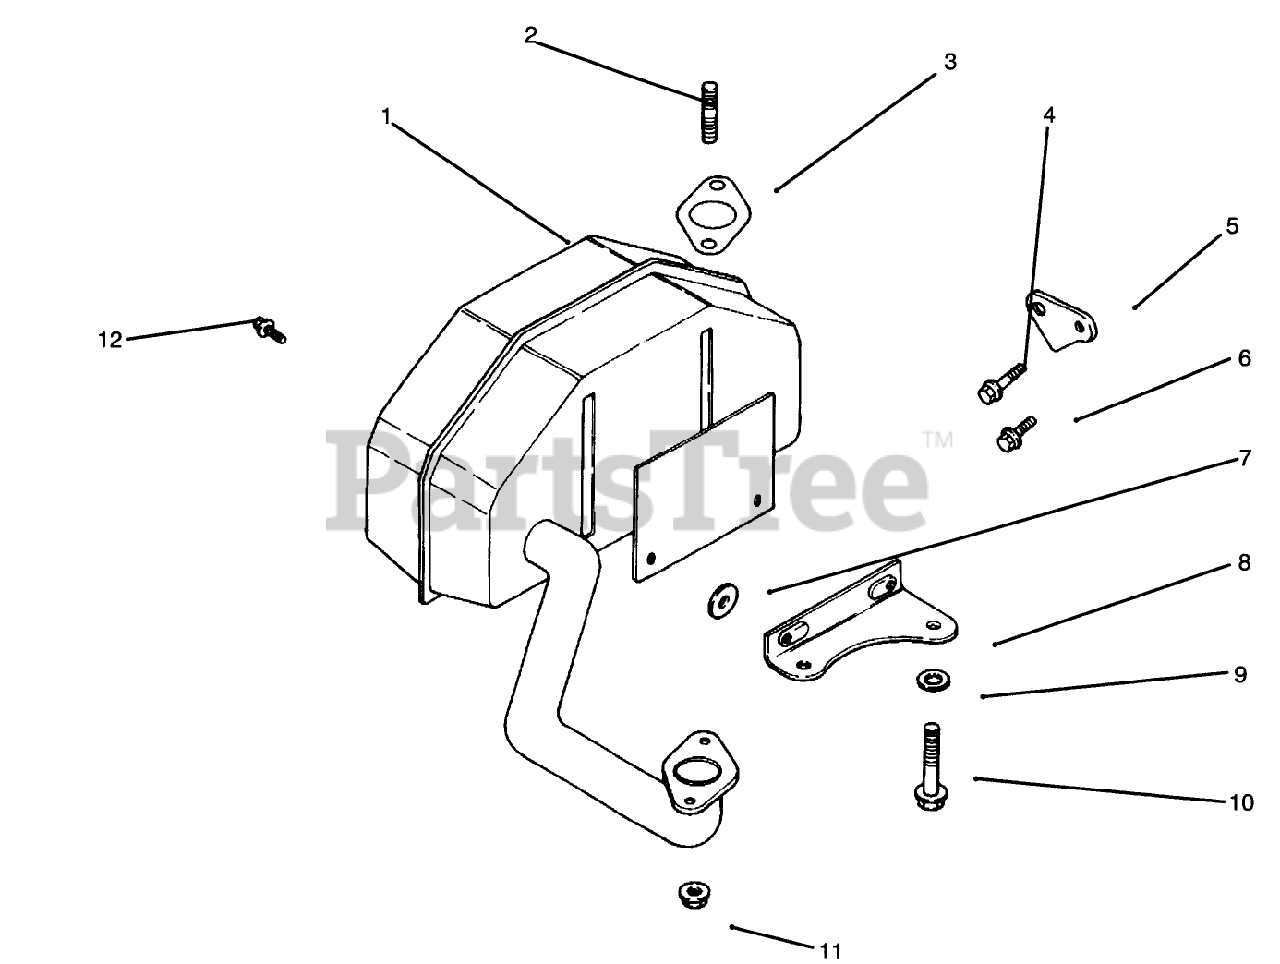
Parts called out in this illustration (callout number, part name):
1	Muffler
3	Gasket-Exhaust Manifold (Only On: 72043, 72042, 72363, 72062)
5	Strap-Lifting (Only On: 72042,72043,72062,72063)
7	Washer
8	Bracket-Muffler
9	Washer (Only On: 72042, 72063, 72062, 72043)
11	Nut-Muffler
